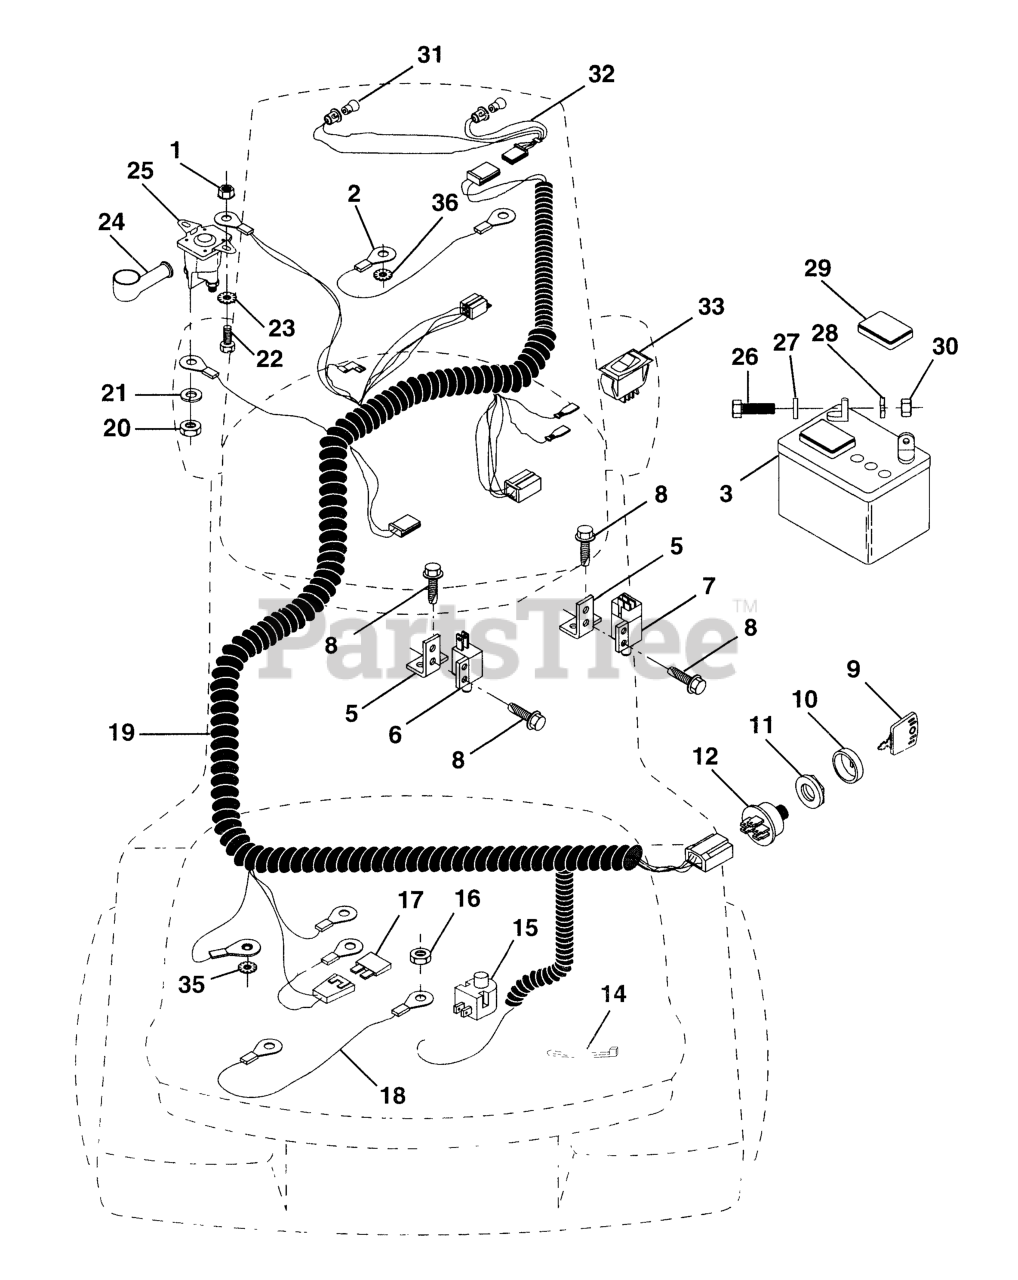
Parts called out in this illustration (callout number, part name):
1	NUT
2	CABLE.BATTERY.6GA.16"RED
3	BATTERY
5	BRACKET LT
6	SWITCH-INTER. GT
7	SWITCH INTERLOCKT
9	KEY.MOLDED.GENERIC
10	COVER KEY IGNITIO
11	NUT IGNITION
12	SWITCH YTV
14	TIE GUIDE
15	RP.SWITCH.PLUNGER.NC.GRAY
16	NUT
18	CABLE ASSY
19	HARNESS IGN
20	NUT
21	LOCKWASHER
22	BOLT
23	Washer, Lock, External Tooth 1/4
24	TERMINAL COVER
25	SOLENOID
26	BOLT.HEX.1/4.X.3/4.DICHROMATE
27	WASHER
28	LOCKWASHER
29	CAP BATTERY NLA
30	NUT
31	SOCKET LIGHT HARNESS
35	LOCKWASHER
36	Washer, Lock, Internal Tooth 1/4
